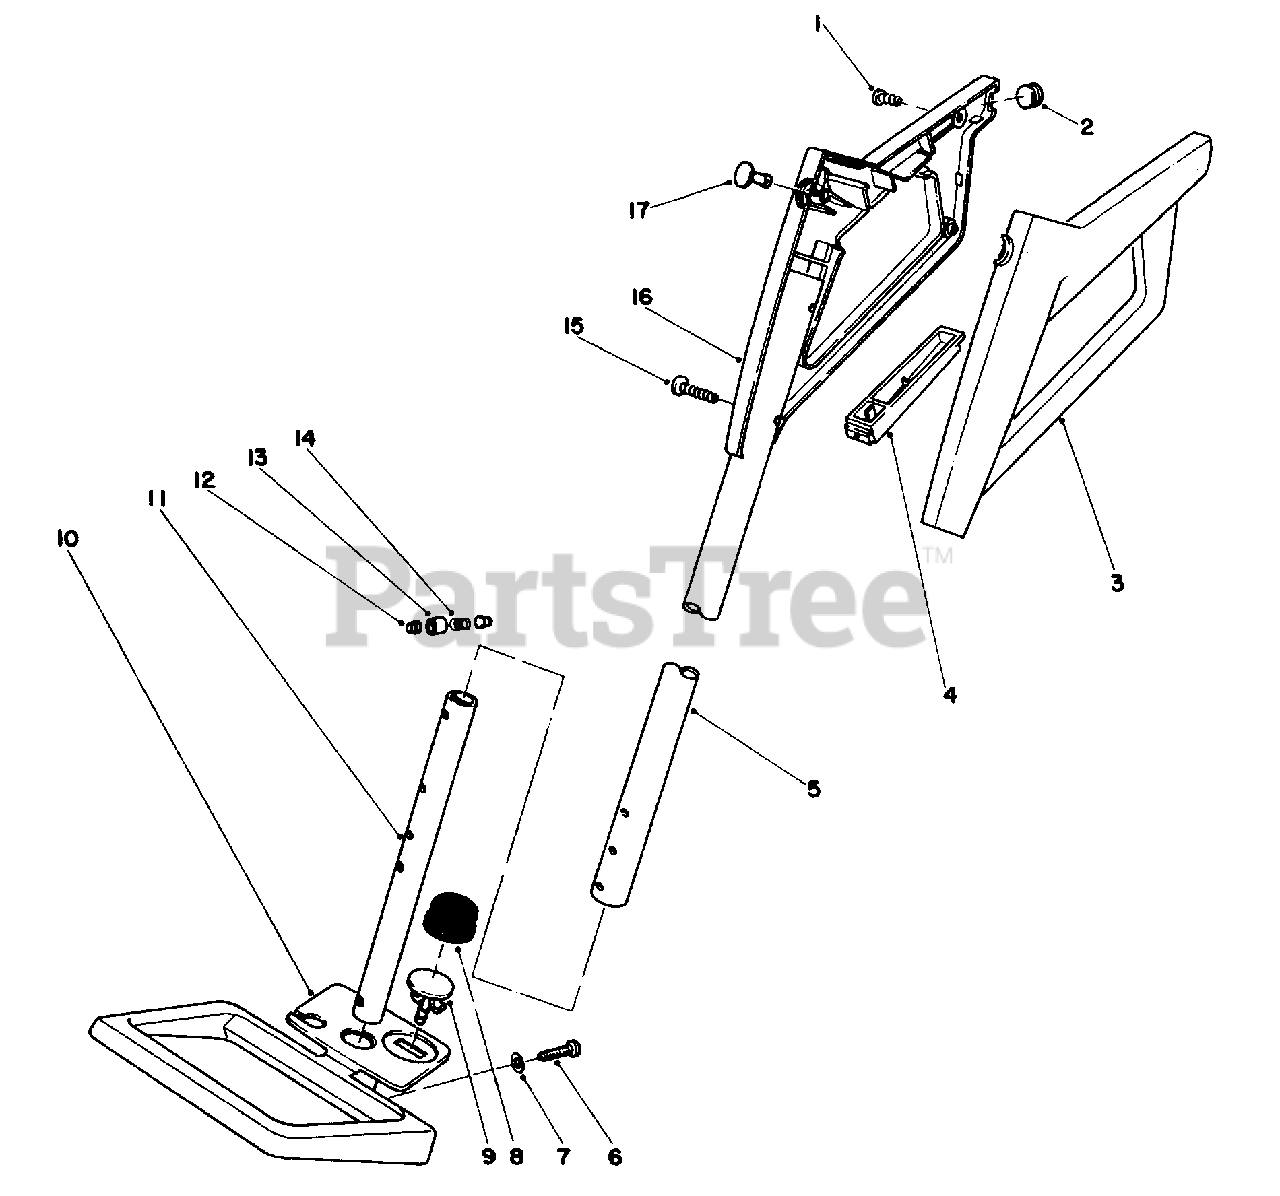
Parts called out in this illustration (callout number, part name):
1	Screw Self-Tapping Cross Recess Pan Hd.
2	Plug-Cord
3	Grip-Control L.H.
4	Cover Handle
5	Tubing-Upper Handle
6	Screw-Machine Slotted Hex Hd.
7	Washer-Plain
8	Bulb-Primer
9	Body-Primer
10	Insert Handle Assembly
11	Tube-Handle, Mounting
12	Release Handle
13	Sleeve Release
14	Spring-Compression
15	Screw-Self Tapping Cross Recess Pan Hd.
16	Grip-Control R.H.
17	Plug Key
